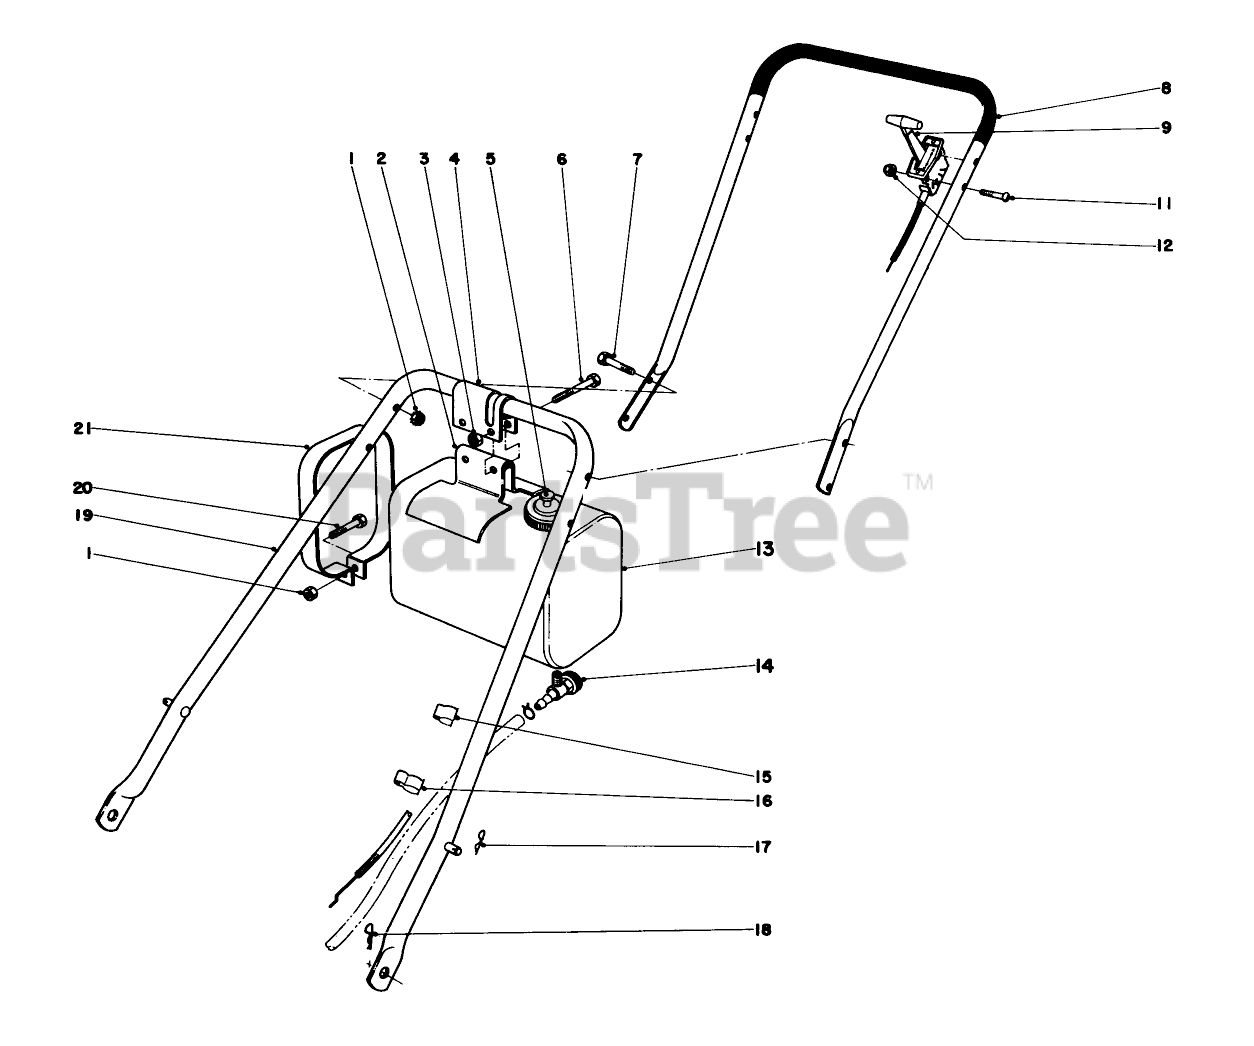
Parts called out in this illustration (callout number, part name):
6	SCREW-HH
7	SCREW-HH
12	NUT-LOCK, NI
17	PIN-COTTER
18	PIN-COTTER, HAIR
20	SCREW-HH
